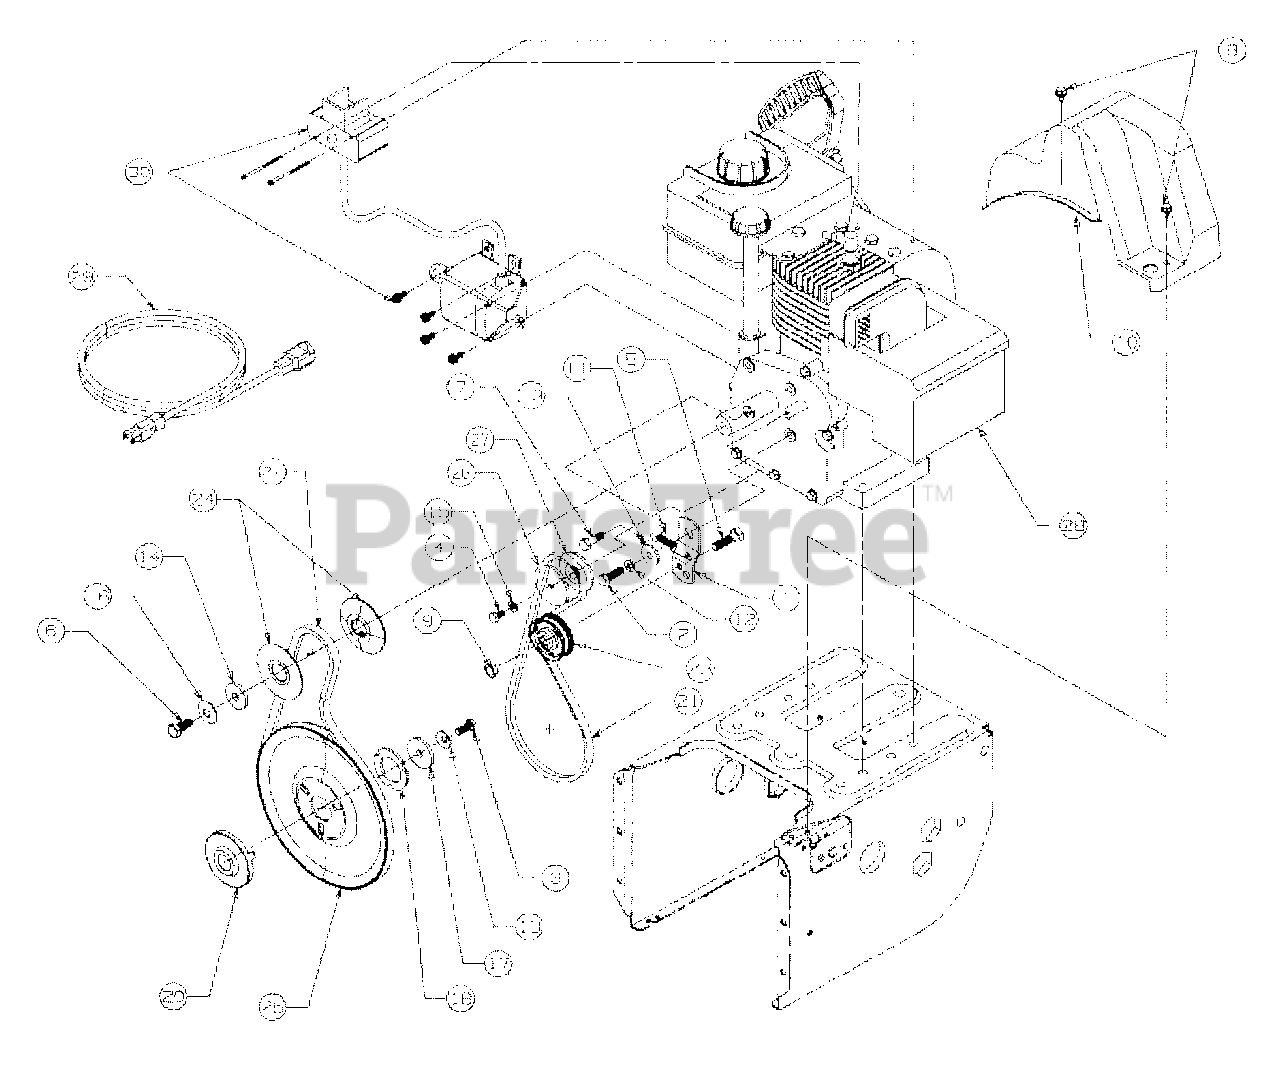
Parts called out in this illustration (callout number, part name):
5	Screw
9	Nut, Hex Jam
11	Spring
15	Washer
18	Washer
20	Pulley, Adapter
21	V-Belt
22	V-Belt Matched
24	Pulley, Half
25	Pulley, Auger
26	Pulley Half
27	Pulley, Half
28	Engine
29	Cord Extension
30	Starter
